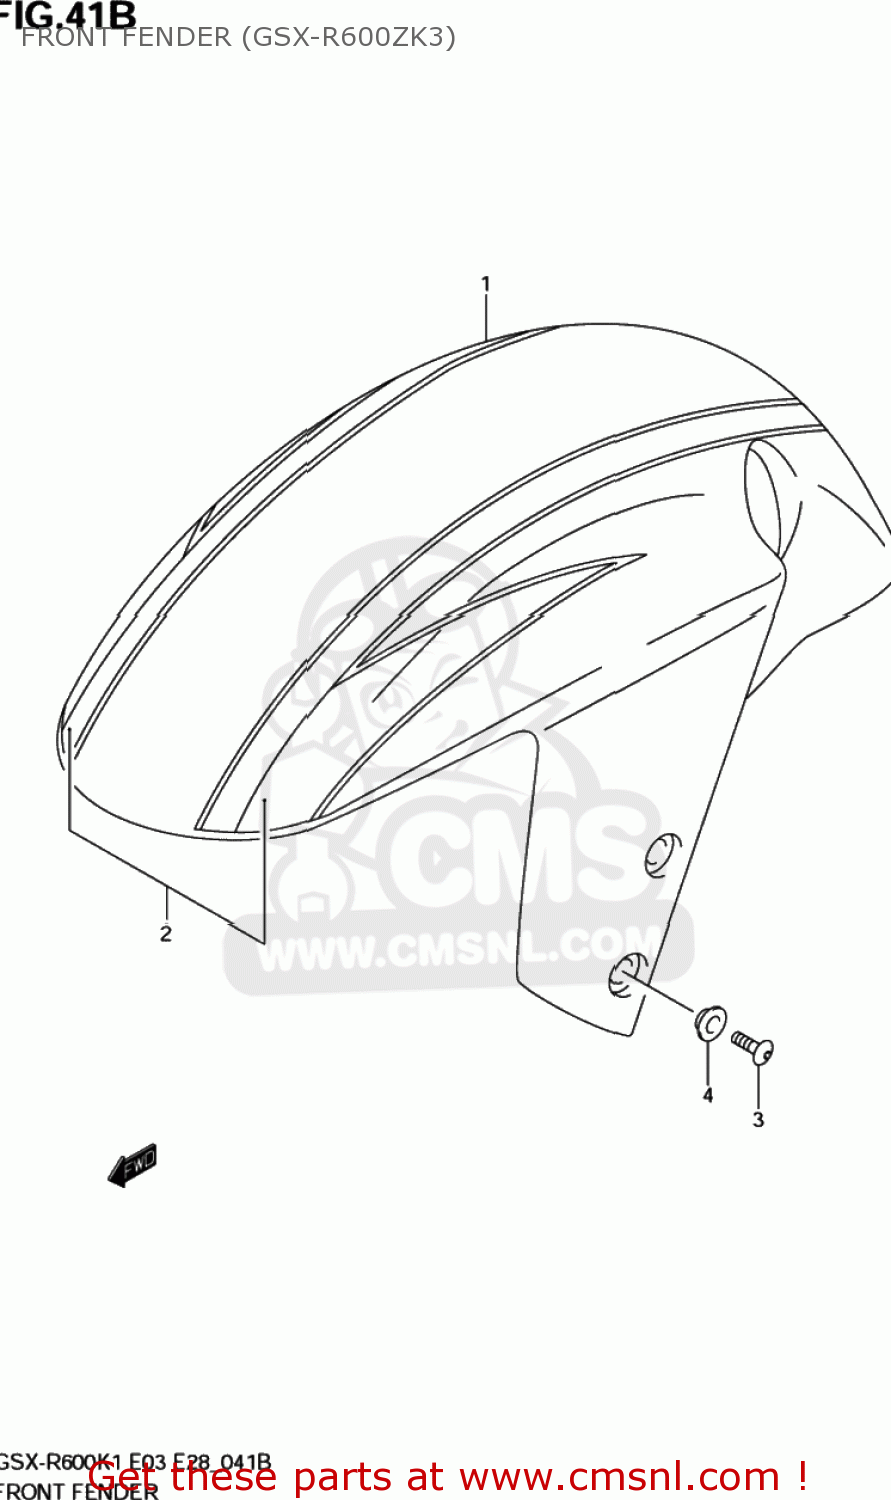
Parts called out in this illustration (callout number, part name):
1	FENDER ASSY,FR
2	TAPE,FR FENDER
3	SCREW(6X16)
4	WASHER(6.3X16X1.5)
